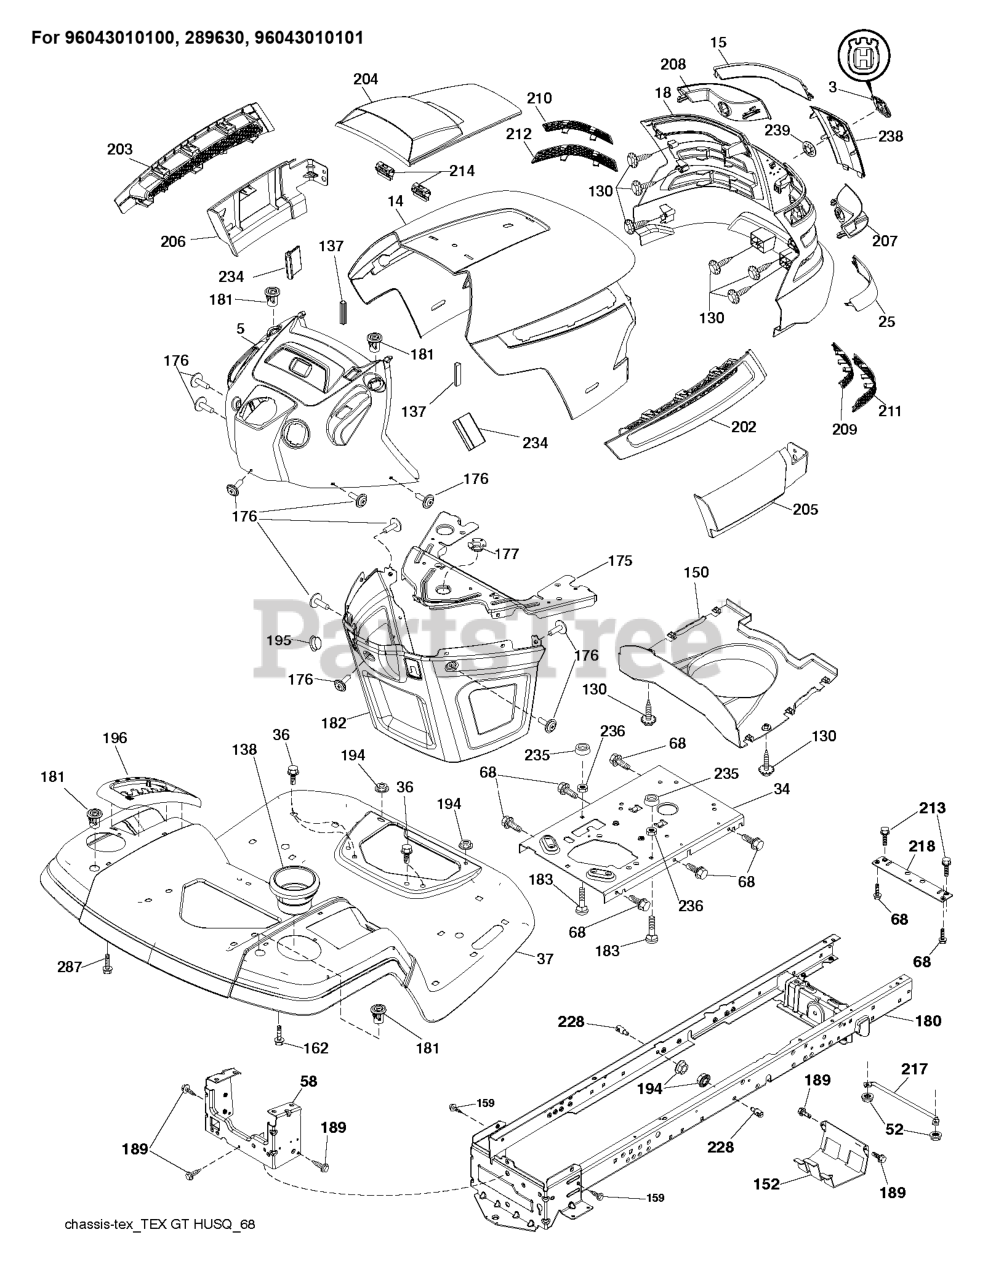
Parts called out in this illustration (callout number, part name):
3	LOGO.HUSQ.GT.LT.CROWN.H
14	HOOD
15	LENS.LH.TEX.GT.HUSQ.CL
18	GRILL.ASM.HUSQ.TG/CRD.W/TRIM
25	LENS.RH.TEX.GT.HUSQ.CL
34	PLATE.ENGINE.WELDED.CHASSIS
36	SCREW 5/16"
37	FENDER.TLT.PDL.CNTRL.W/CPH.ORG
52	LOCKNUT
58	DRAWBAR UPPER 2PC SMALL FENDER
68	Screw 5/16-18 x 1/2 Hex, Self Tapping 5/16-18 x 1/2
130	SCREW.#10 X 0.750.BOS
137	BUMPER DASH
138	CUPHOLDER.TL.TEX.418
150	AIR.DUCT.HOOD.TEX.GT.HUSQ
152	SHIELD.BROWNING.W/TEX
159	SCREW, 3/8-16X3/4
162	SCREW.HI-LO.CONSOLE
175	PLATE.CROSSMEMBER.HUSQ
176	SCREW.#10-24X5/8.RN.QU
177	BUSHING, STEERING
180	CHASS.WLDMNT.TL.12GA/2P.48/54
181	BUSHING.MNT.FEND.CRGO.
182	DASH.LOWER.COMMON.12V.ADAPTOR
183	BOLT.5/16-18X1-1/4 FULL THD
189	SCREW
194	NUT LOCK HEX FLANGE 5/16-18
195	PLUG.HOLE.DASH.LOWER.12V.BLK
196	RP CONSOLE.ASM.DECKLFT.GR/RBT.
202	VENT.SIDE.HOOD.HUSQ.RH.GREY
203	VENT.SIDE.HOOD.HUSQ.LH.GRAY
204	HOOD VENT
205	SKIRT.HOOD.SIDE.HUSQ.RH.GREY
206	SKIRT.HOOD.SIDE.HUSQ.LH.GREY
207	BEZEL.RH.TEX.GT.HUSQ
208	BEZEL.LH.TEX.GT.HUSQ
209	INSERT.HEX.GRILL.HUSQ.GREY
210	INSERT.HEX.GRILL.HUSQ.
211	INSERT.HEX.GRILL.HUSQ.
212	INSERT.HEX.GRILL.HUSQ.
213	BOLT
214	CLIP.RETAINER.TINNER.
217	ROD.PIVOT.HOOD
218	X-PIECE.HOOD.STOP.NON/
228	STUD.FASTNER.W/ANTI-ROTATE
234	BUMPER.HOOD.TEX.HUSQVARNA
235	SPACER FENDER
236	NUT.CENTERLOCK.5/16-
238	TRIM.HUSQ.TG/CRD.SERVICE
239	NUT PUSH M
287	SCREW 1/4X20
